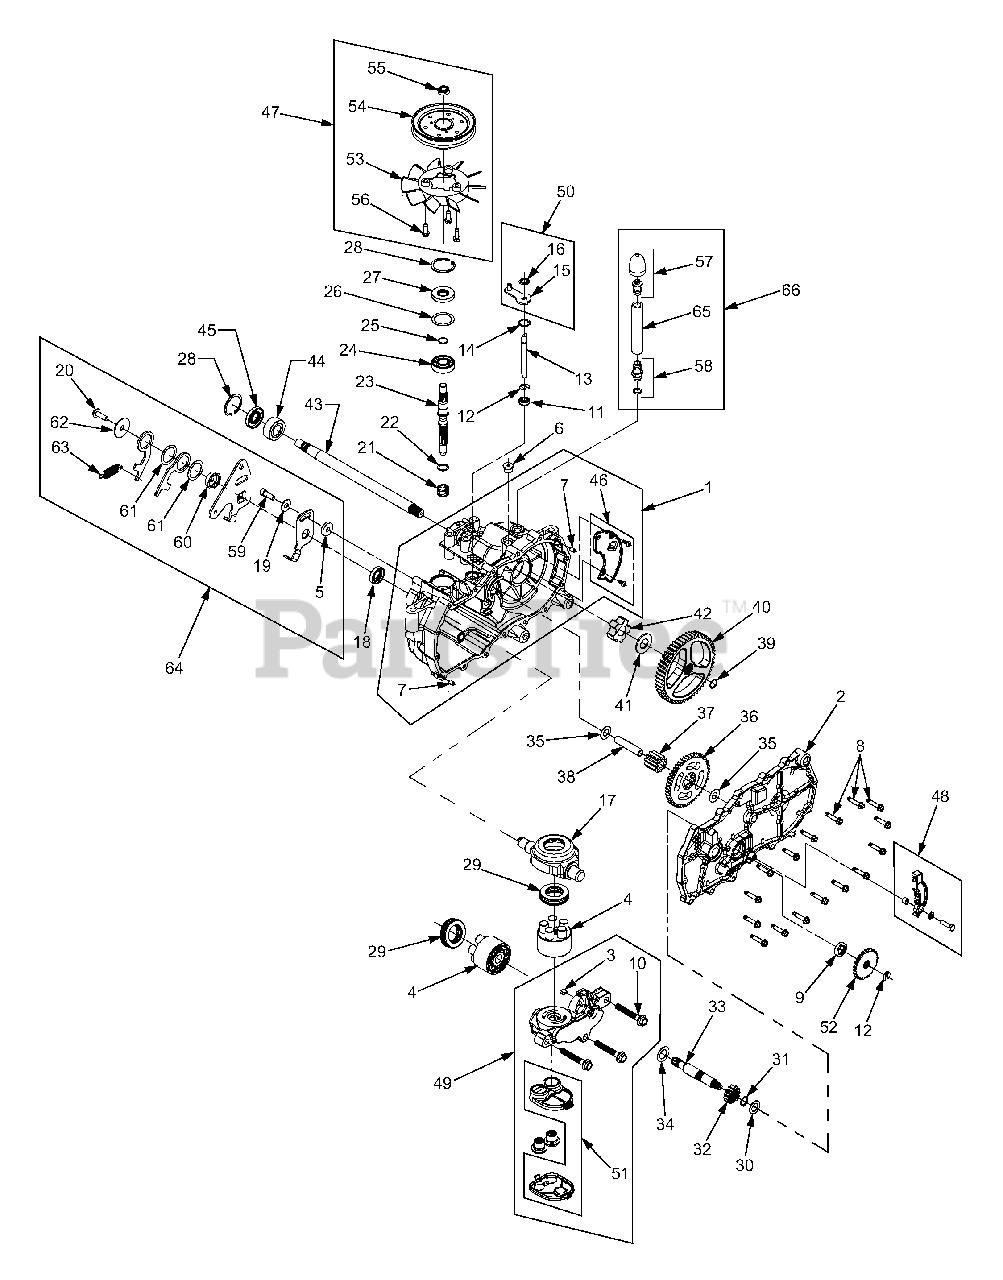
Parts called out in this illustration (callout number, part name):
1	Housing Assembly, Main RH
2	Side Assembly, RH
3	Plate, Bypass
4	Block Assembly
5	Spacer, .32 x 1.005
7	Pin, Stainless
8	Screw, Hex Self Tapping, 1/4-20 x 1.25
9	Seal, Lip, .625 x 1.0 x .25
10	Bolt, Hex Flange, 3/8-24 x 2.5
11	Seal, Lip, .375 x .75 x .25
12	Ring, Retaining, .375 Ext.
13	Rod, Bypass
14	Ring, Retaining, .75 Int.
15	Arm, Bypass
16	Ring, Retaining, .375 Push
17	Swashplate, Trunnion
18	Seal, Lip, 18 x 32 x 7
19	Washer, Flat, 11/32 x 7/8 x 1/16
20	Screw, 5/16-24 x 1.0
21	Spring, Compression
22	Washer, .591 x .787 x .04
23	Shaft, Input
24	Bearing, Ball, 17mm x 40 x 12
25	Ring, Wire Retaining, .561
27	Seal, Lip, 17 x 40 x 7
28	Ring, Retaining
29	Bearing, Thrust, 30 x 52 x 13
30	Washer, Flat, 5/8 x 1.0 x .05
31	Ring, Retaining
32	Gear, Pinion, 13T
33	Shaft, Motor
34	Washer, .71 x 1.16 x .04
35	Washer, HT, .5 x 1.0 x .032
36	Gear, 10T/48T
37	Gear, Jackshaft, 10T
38	Pin, Jackshaft
39	Ring, Spiral Retaining
40	Gear, Bull, 52T
41	Washer, 3/4 x 1.5 x .13
42	Bearing, Sleeve
43	Axle, spline
44	Bushing, .752 x 1.571 x .625
45	Seal, Lip, .75 x 1.577 x .25
46	Kit, Expansion Plate RH
47	Kit, Fan-Pulley
48	Kit, Brake Arm
49	Kit, Center Section-Filter RH
50	Kit, Bypass Arm
51	Kit, Filter
52	Disc, Brake Cog
53	Fan, 6" 10 Blade
54	Pulley, 4.5
55	Nut, Hex Insert Lock, 1/2-20
56	Screw, Hex Wash. Hd. Tapp 1/4-20
57	Cap Assembly, Vent
58	Fitting/O-ring Assembly
59	Screw, Patch, 5/16-24 x 1.0
60	Bushing, Pilot, 1.125
61	Washer, Plastic
62	Washer, 1.5 x .34 x .062
63	Spring, Extension
64	Kit, Return Assembly RH
65	Hose, .5 x 4.0
66	Kit, Breather Assembly
